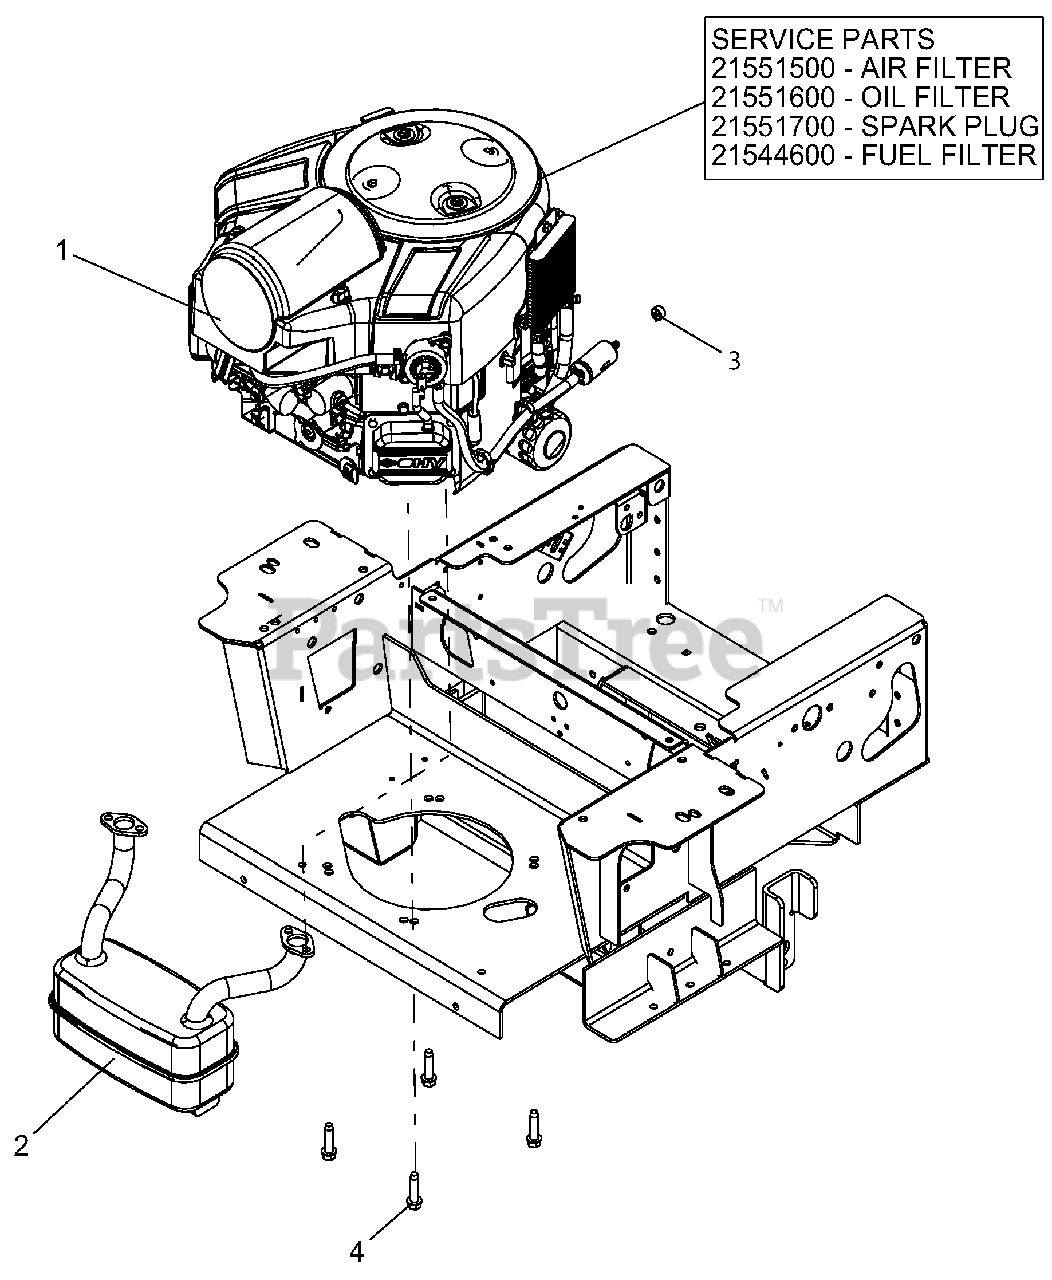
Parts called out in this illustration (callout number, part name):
1	ENGINE, BRIGGS 724CC VERT SHAFT
1	AIR FILTER
1	OIL FILTER
1	SPARK PLUG
1	FUEL FILTER
2	ASM, MUFFLER
3	CLAMP, FUEL LINE
4	SCR-TAP .38-16X1.50 HWH TR YZ
